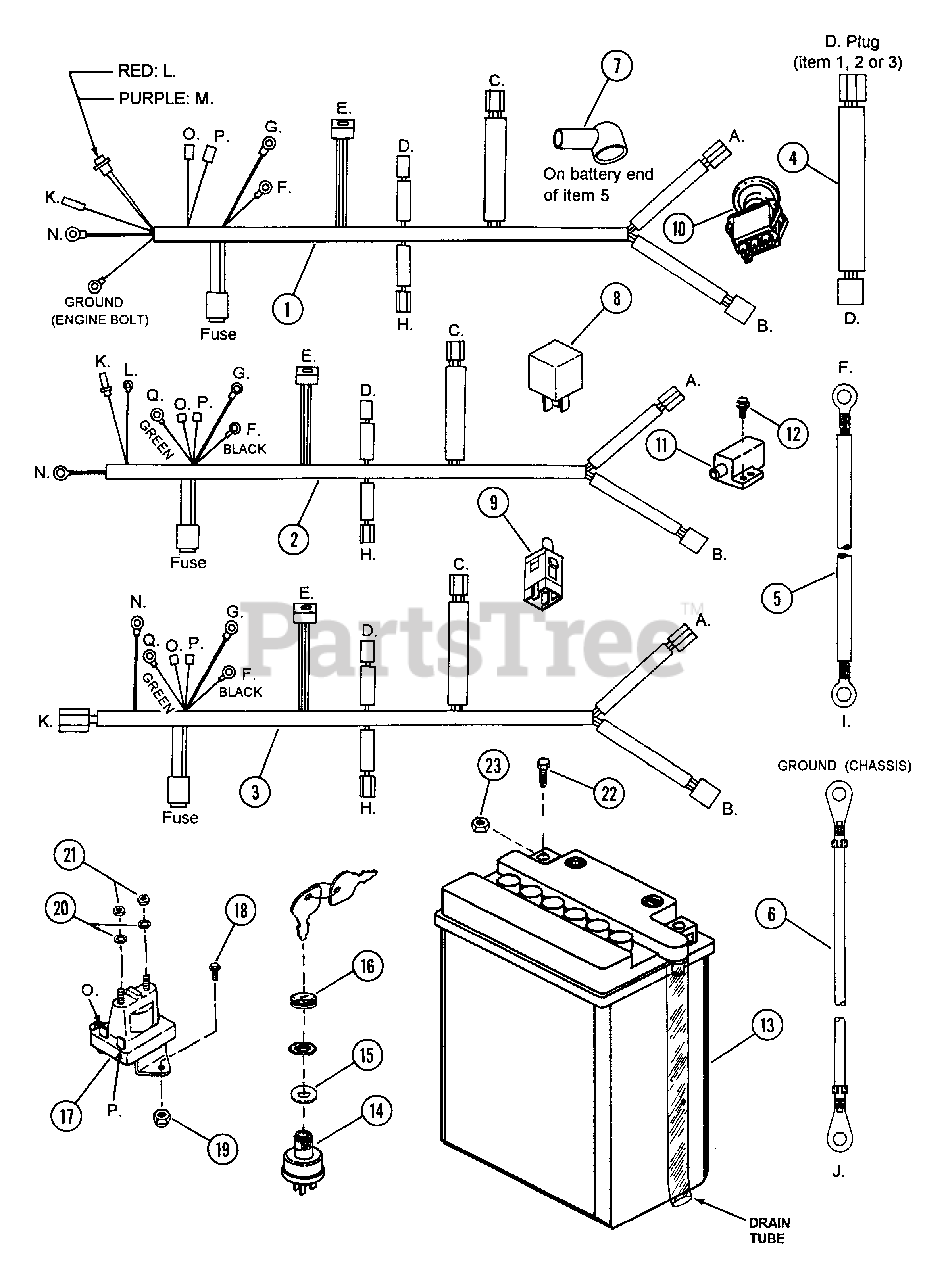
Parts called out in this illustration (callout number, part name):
1	WIRING HARNESS (Briggs 14HP)
2	WIRING HARNESS (Briggs 16HP)
3	WIRING HARNESS (Kohler 15HP)
4	WIRING HARNESS, Warner Clutch
5	WIRE, Positive, 13"
6	WIRE, Negative, 14"
7	COVER, Battery Cable
8	RELAY, Operator Presence Control
9	SWITCH, Seat
10	SWITCH, PTO Electric Clutch
11	SWITCH, Park Break
12	SCREW, #10-24 x 1/2" Hex Washer Self-Tap (Torx)
13	BATTERY, 12 Volt, 14 Amp, 190 Cold Cranking Amp
14	SWITCH, Ignition (After-fire Solenoid)
16	BEZEL
17	SOLENOID, 12 Volt
18	SCREW, 1/4-20 x 1/2" Hex Head Cap, Grade 5
19	NUT, 1/4-20 Hex Flange Lock, Grade 5
20	WASHER, 1/4 Internal Tooth Lock
21	NUT, 1/4-20 Hex Jam
22	SCREW, #10-24 x 1/2" Hex Head Cap
23	NUT, #10-24 Twin "Whiz" Lock
